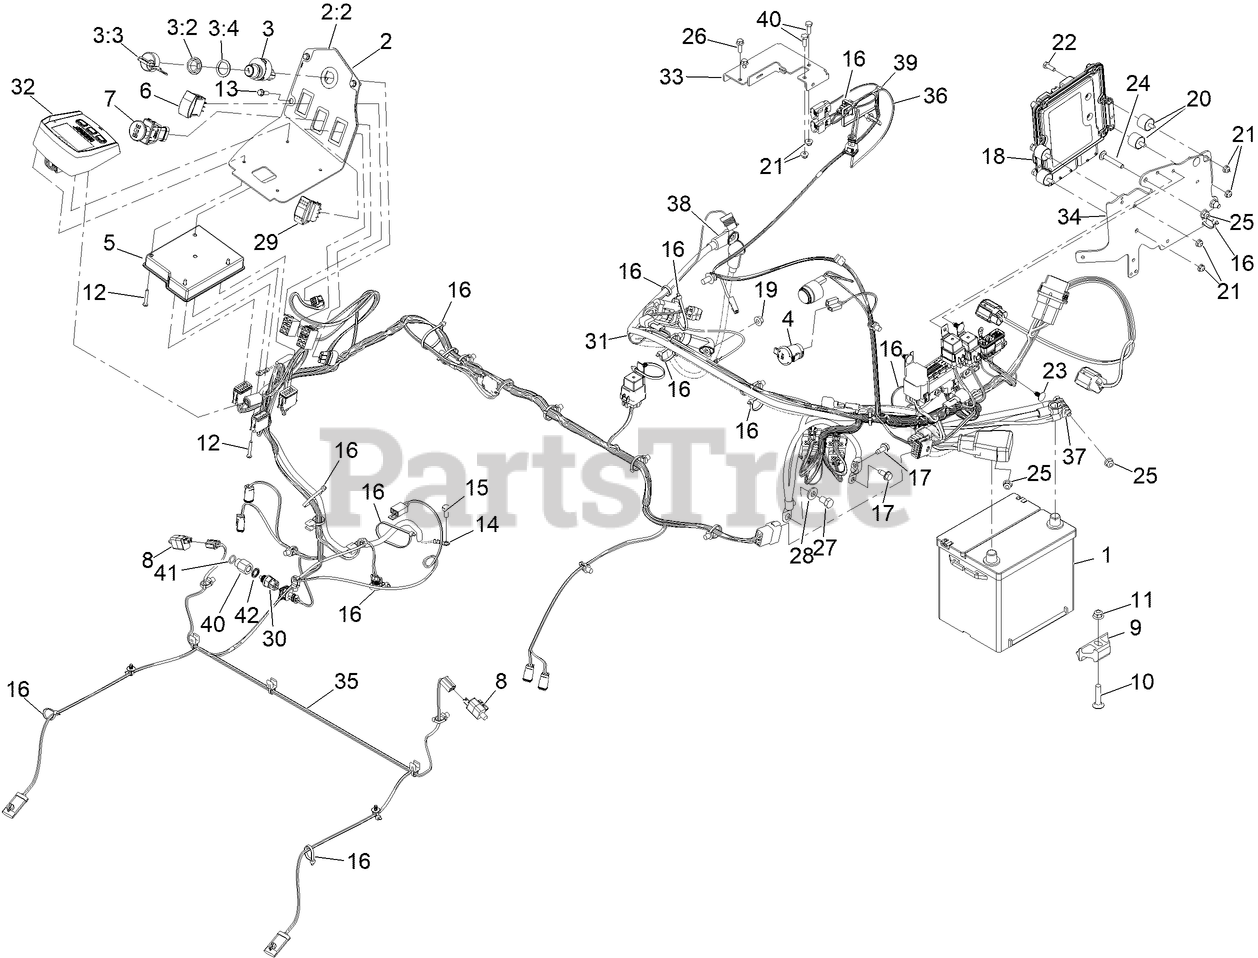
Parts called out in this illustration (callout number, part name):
1	BATTERY-DRY
2	ASM, CONSOLE W/ DECAL 144
2:2	DECAL-CONTROL PANEL
3	IGNITION SWITCH ASM
3:2	NUT-MOUNTING
3:3	IGNITION KEY SET
3:4	WASHER-BACKUP
4	PORT-POWER, 12V
5	MODULE-MCU
6	SWITCH
7	SWITCH-PTO, SEALED
8	SWITCH
9	RETAINER-BATTERY
10	SCREW-CARR
11	NUT-HF, NI
12	SCREW-PPH
13	SCREW-HWH
14	HARNESS-WIRE, JUMPER
15	BOLT
16	TIE-CABLE
17	SCREW-HWHTF
18	CONTROLLER-ENGINE
19	NUT-HF
20	MOUNT-CYLINDRICAL
21	NUT-HF
22	SCREW-HH
23	PLUG-PLASTIC
24	BOLT-CARR
25	NUT-HF, NI
26	SCREW-HHF
27	SCREW-HH
28	WASHER-BELLEVILLE
29	SWITCH-ROCKER, ON-NONE-ON
30	SENSOR-TEMPERATURE
31	CLIP-TIE
32	MODULE-HORIZON
33	BRACKET-SENSOR, DPF
34	PLATE-ECU MOUNT
35	HARNESS-WIRE, MAIN
36	HARNESS-WIRE, ENGINE
37	CABLE-BATTERY, RD AND BK ASM
38	CABLE-BATTERY, BK ASM
39	TIE-CABLE
40	FITTING-STR, 6MORB-M12, STL, CZ
41	O-RING
42	WASHER-SEAL, M12
